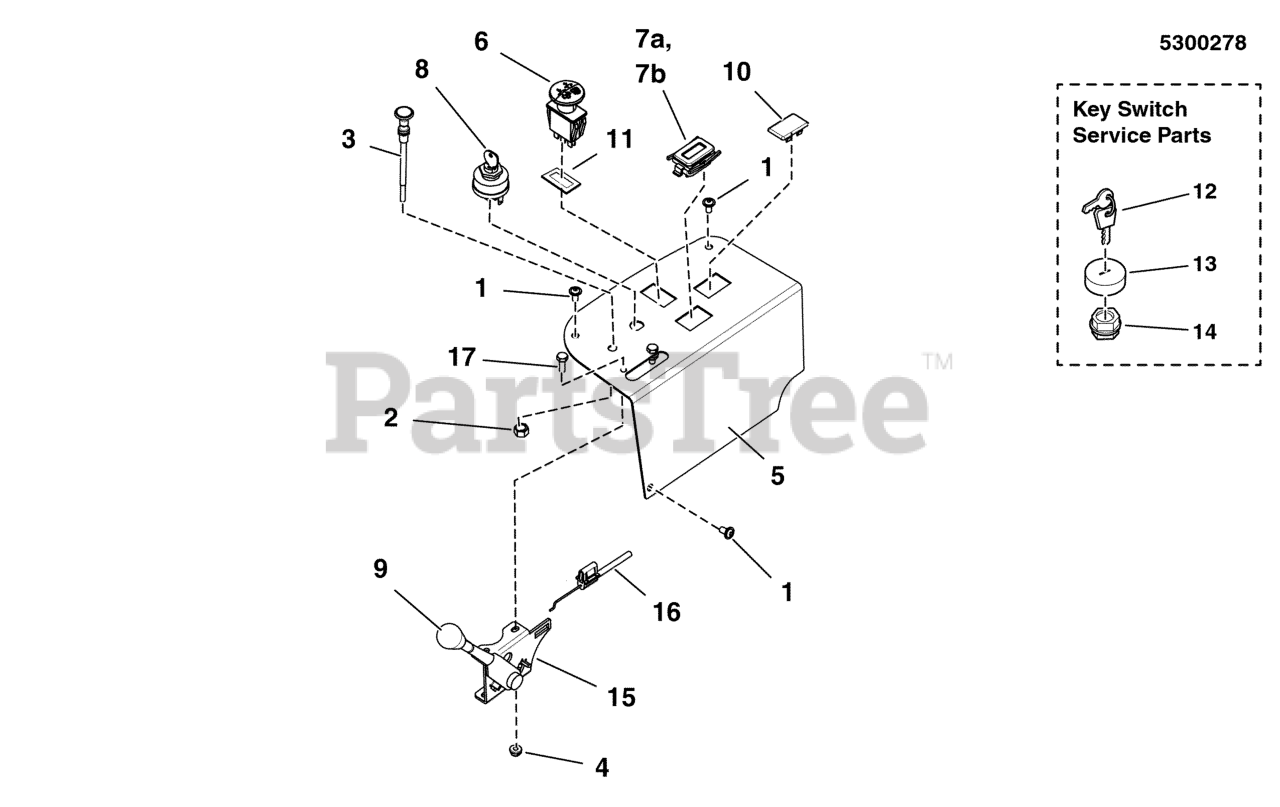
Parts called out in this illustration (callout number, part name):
1	SCREW, ALLEN HEAD 1/4-20X.500 ZINC PHOS
2	NUT, 3/8-24 HEX (SV)
3	CABLE, CHOKE CONTROL, 51" (Z)
4	NUT, Hex, Nylon Lock, #10-24
5	PANEL, Control - Black
6	SWITCH, BLADE ENGAGEMENT
8	SWITCH, IGNITION, 6 POST
9	THROTTLE CONTROL HANDLE/KNOB
10	PLUG, .820X1.44 HOLE, BLACK PLASTIC
11	RING, SWITCH RETAINER
12	KEY, IGNITION MOLDED SET
13	COVER, PLASTIC, SNAP ON
14	PLASTIC NUT
15	LEVER, THROTTLE CONTROL, HEAVY-DUTY
16	CABLE, THROTTLE, 52"
17	SCREW, #10-24 X 3/4" ROUND PHILLIPS
